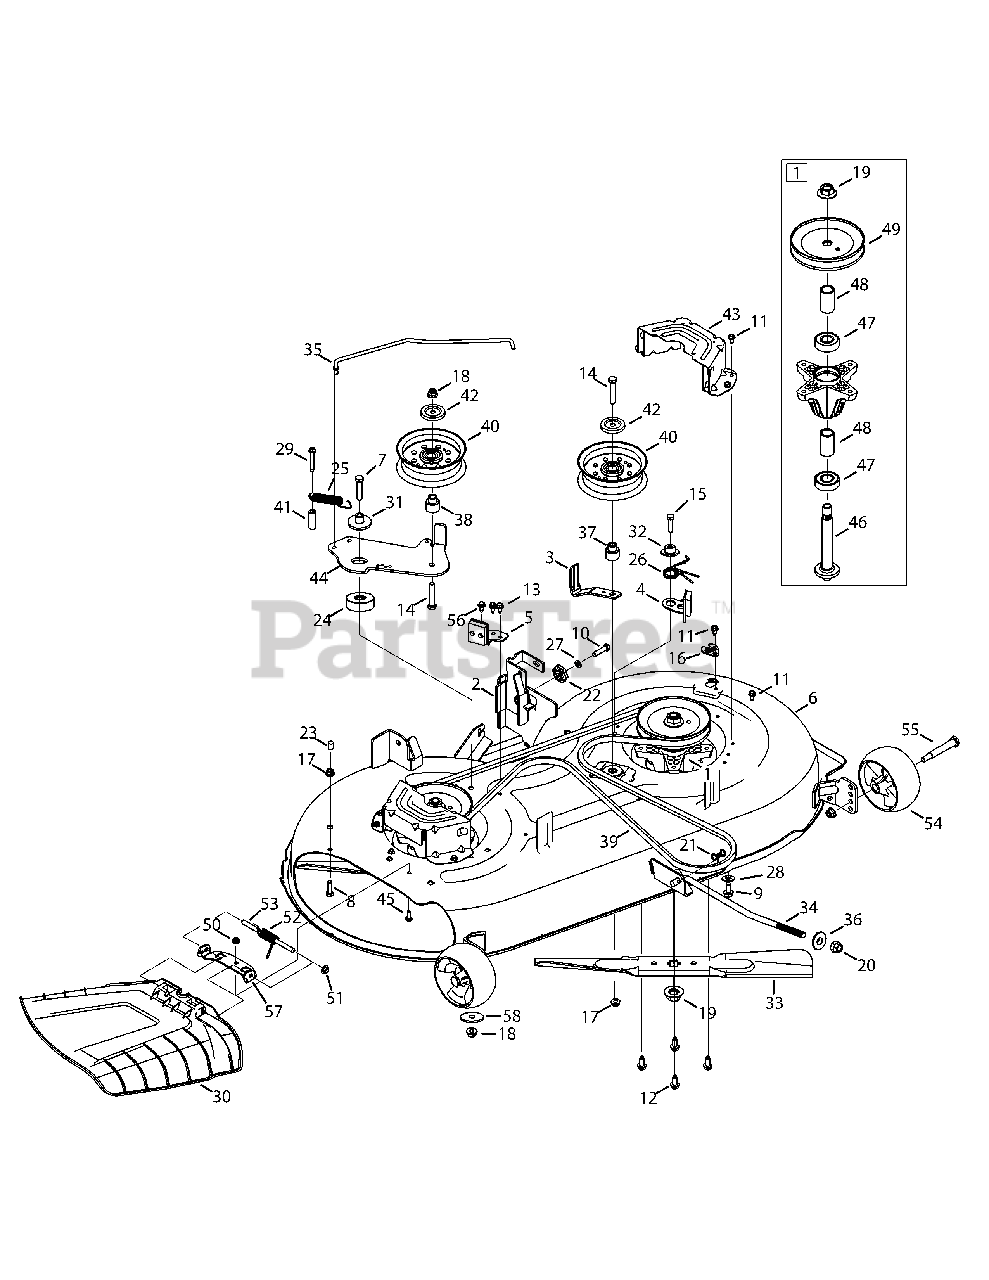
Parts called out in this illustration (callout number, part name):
1	Spindle Ass’y, Pulley, 6.2 Dia
2	Bracket Ass’y, Deck, Hanger LH
3	Belt Keeper
4	Brake Assembly, Deck, LH
5	Brake Assembly, Deck, RH
6	Deck, 42"
7	Hex Screw, 3/8-16 x 1.75
8	Hex Cap Screw, 5/16-18 x 1.00
9	Screw, Self-tapping, 5/16-18, .750
10	Hex Screw, 5/16-18, 1.25, Gr5, Std
11	Screw, Self-tapping, 1/4-20, 0.500
12	Screw, 5/16-18 x 0.750
13	Screw, M6-1 x .625
14	Hex Screw, 3/8-16, 2.00, Gr8, Std
15	Hex cap Screw, 5/16-18 x 1.25
16	Deck Wash Plug
17	Nut, Flange Lock, 5/16-18, Grf
18	Nut, Flange Lock, 3/8-16, Grf
19	Nut, Flange, 5/8-18
20	Flange Lock Nut, 1/2-13
21	Bow-Tie Cotter Pin
22	Gear, Deck, Adjustment
23	Cap, .290 x .500
24	Spacer, .385 x 1.75 x .585
25	Extension Spring, .750 X 4.77
26	Torsion Spring, LH
27	Washer, Lock, 5/16, Regular Duty
28	Flat Washer, .406 x .875 x .059
29	Screw, Self Tapping, 1/4-20, 1.50
30	Chute Deflector Assembly
31	Shoulder Spacer, .970 x .190
32	Shoulder Spacer, .75 x .145
33	Blade, Cut, 21.23" 2-In-1, Econ
34	Rod, Lift, Deck, Frt, 12.7
35	Brake Rod
36	Deck Lift Pivot Cup
37	Shoulder Spacer, Idler
38	Shoulder Spacer, Pivot Idler
39	Belt, V Type, A Sec X 96.5
40	Pulley, Idler, 4.50"Dia
41	Spacer, .260 x .375 x 1.030
42	Pulley Cap
43	Deck Belt Cover, 42
44	Deck Idler Bracket
45	Hex Cap Screw, 1/4-20 x .62
46	Shift, Spindle, 6.11.
47	Bearing, Ball, .787id x 1.85 Odx.551
48	Spacer, .792 x 1.060 x 1.860
49	Pulley, Deck, 5.4 Dia
50	Nut, Flange Lock, 1/4-20, Nylon
51	Push Cap
52	Spring, Torsion, .440 ID x 1.75
53	Hinge Pin
54	Wheel, Deck, 5.0 Dia Ball
55	Bolt, Shoulder, .496 x 2.50, 3/8-16
56	Shoulder Screw, 1/4-20
58	Flat Washer, .406 x 1.50 x .105
